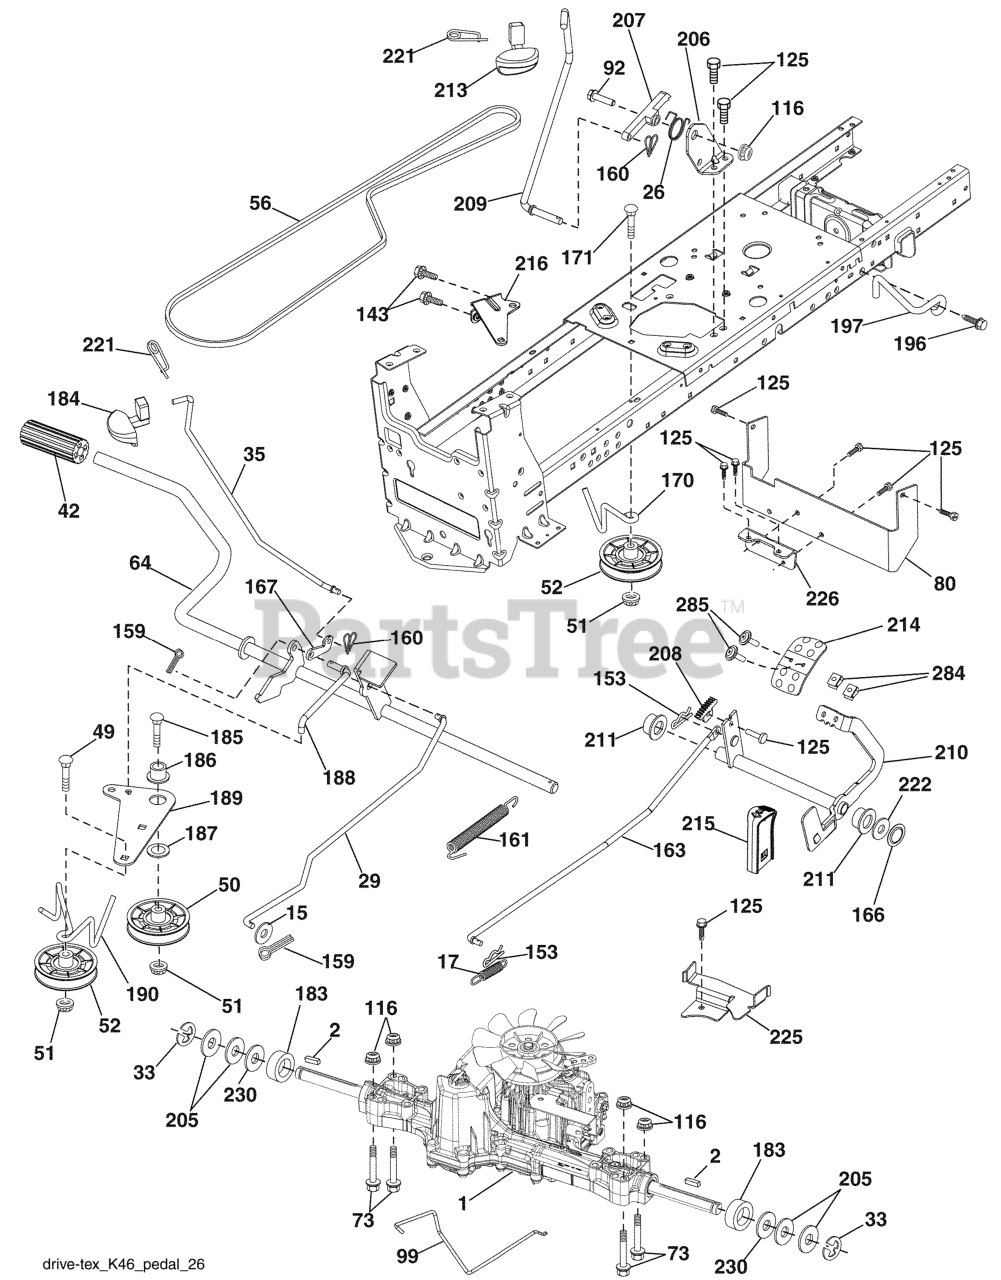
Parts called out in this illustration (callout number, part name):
1	TRANSAXLE, TUFFTORQ K46
2	SQUARE KEY
15	WASHER
17	SPRING.BRAKE.K46.GREEN
26	SPRING.RETURN.CRUISE
29	ROD.BRAKE.K46
35	ROD.BRAKE.PARKING.GT.H
42	PEDAL COVER T
50	IDLER.FLAT.910.OFFSET
51	NUT LOCK FLG 3/8-16 UNC
52	IDLER.V-GROOVE.910.OFFSET
56	V-BELT.MOWER.92.40.42/K46
64	SHAFT.ASM.PEDAL.BRK.CNTR
73	BOLT HEX 5/16-18 GR 5
80	STRAP TORQUE.ASM.K46/18"TEX
92	BOLT
99	ROD.SPRING.BYPASS.K46.LT.Z
116	NUT LOCK HEX FLANGE 5/16-18
125	SCREW
143	Screw 5/16-18 x 1/2
153	RETAINER M
159	COTTER PIN
160	RETAINER CLIP
161	SPRING, RETURN LT
163	ROD.CONTROL.PEDAL.K46
166	NUT.PUSH.625.2006
167	LATCH.BRAKE.SPRING
170	KEEPER.V-IDLER.CENTER.
171	BOLT
183	SPACER AXLE
184	HANDLE.PARKG.BRK.HUSQ X667
186	SPACER.RETAINER
187	WASHER 12/32X2X10GA
188	RP.LINK.CLUTCH.GROUND.DRIVE
189	BELLCRANK.GROUND.DRIVE.TEX.
190	KEEPER.BELLCRANK.DRIVE
196	SCREW 3/8-16X1
197	LINK.CLUTCH.ANIT-ROTAT
206	BRKT.MOUNT.LATCH.CRUIS
207	LATCH.CONTROL.CRUISE
208	GEAR.SECTOR.CONTROL.CR
209	ROD.CONTROL.CRUISE.GT.
210	ROCKER.ASM.PEDAL.CONTR
211	BEARING.NYLON
213	KNOB.CONTROL.CRUSIE.HU
214	PEDAL.FORWARD.HUSQVARNA.DEALER
215	PEDAL.REVERSE.TEX.GT.4
216	BRACKET.PULLEY.IDLER.W/TEX
221	RETAINER.SPRING.CLIP.H
222	WASHER 21/32 X 1-1/4 X 10 GA.
225	KEEPER.BELT.TRANSAXLE.K46
226	BRACKET.MOUNT.TORQUE.K46.TLT
230	WASHER.HARDENED
284	NUT.U-CHNL.1/4-20.550DP.350PNL
285	SCREW.PHD.1/4-20.BOX DRVE
